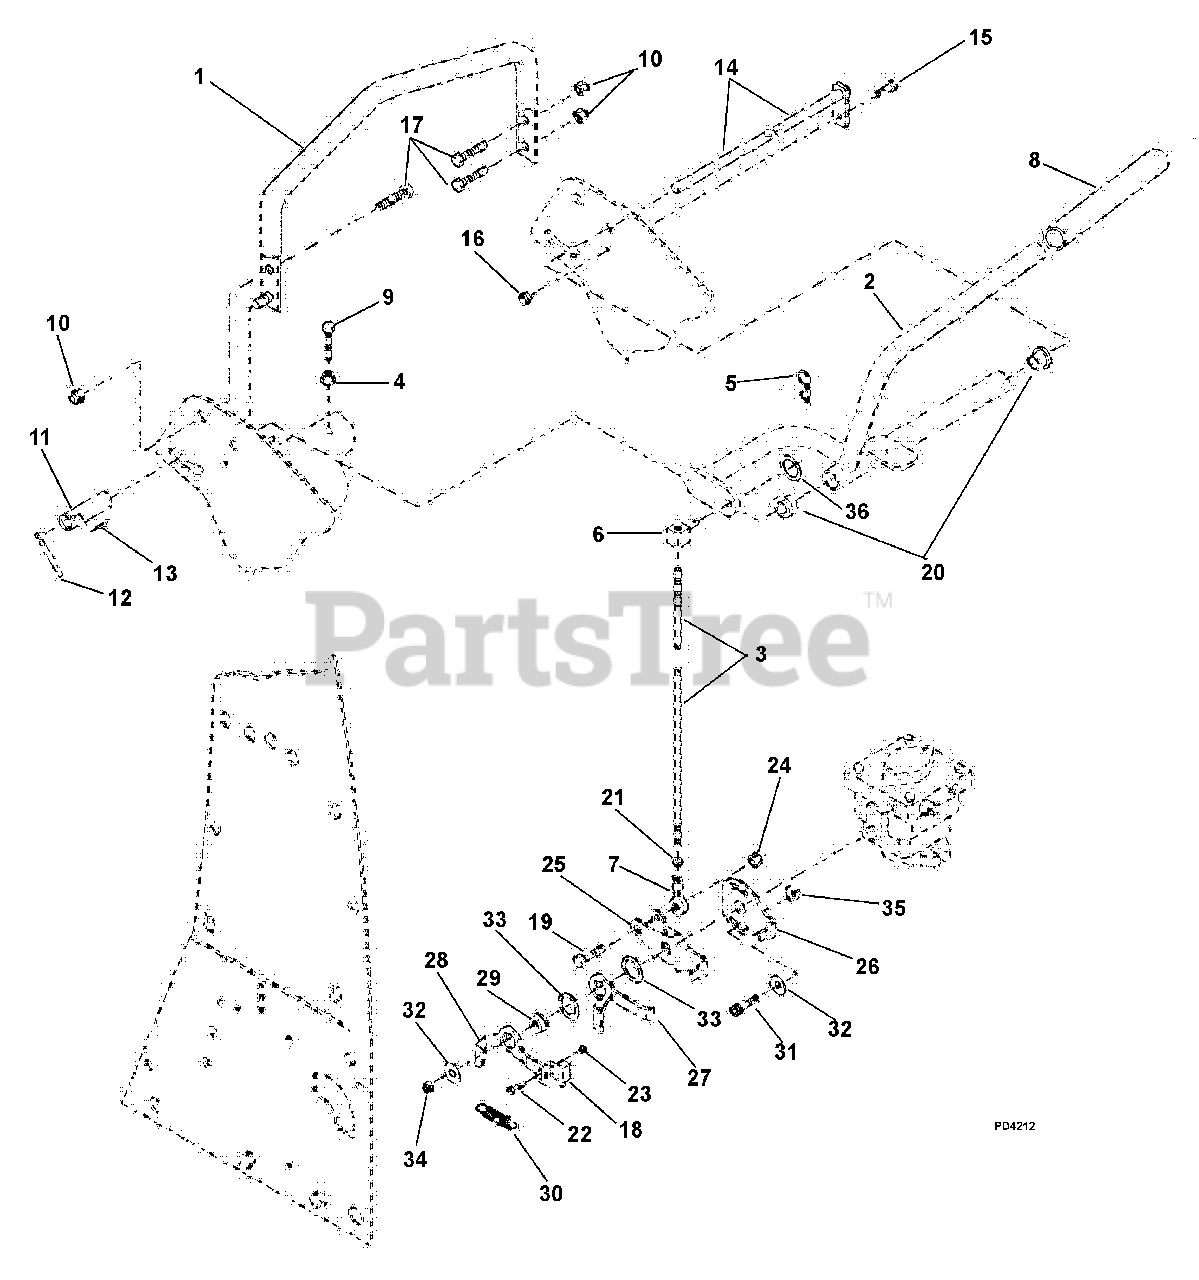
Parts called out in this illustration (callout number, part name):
1	Speed Limiter
2	Weldment, LH SS Control Lever
3	Control Rod
4	Flange Nut, M16 x 1.0
5	Spring Pin
6	Swivel
7	Rod End, 5/16 RH -Female
8	Grip, Control
9	Cap Screw, Reverse Stop M6 x 1
10	Nut, Lock, Nylon M10-1.5
11	Base, Speed Control Lock
13	Pin, Spring 5/32 x 1
14	Shaft, Pivot
15	Cap Screw, M6 x 1.0 x 20
16	Lock Nut, Flat, ISO 7043, M6 x 1.00-10
17	Bolt, Hex M10 x 1.5 x 25
18	Switch, Stop (Double Pole) N.O.
19	Bolt, Hex .31-18 x 1.00
20	Bushing
21	Nut, Jam .31-24
22	Bolt, Hex M5-.8 x 16
23	Nut, Hex M5 x .8
24	Nut, Lockinig, Center .31-18
25	Arm, Control Return
26	Arm, Return
27	Arm, RH Inner Return
28	Arm, LH Outer Return
29	Spacer
30	Spring
31	Screw, 5/16 x 1 Patch Lock
32	Washer
33	Washer, Nylon
34	Nut, Center Lock .31-24
36	Washer, Flat, Steel .406 x .812 x .065
